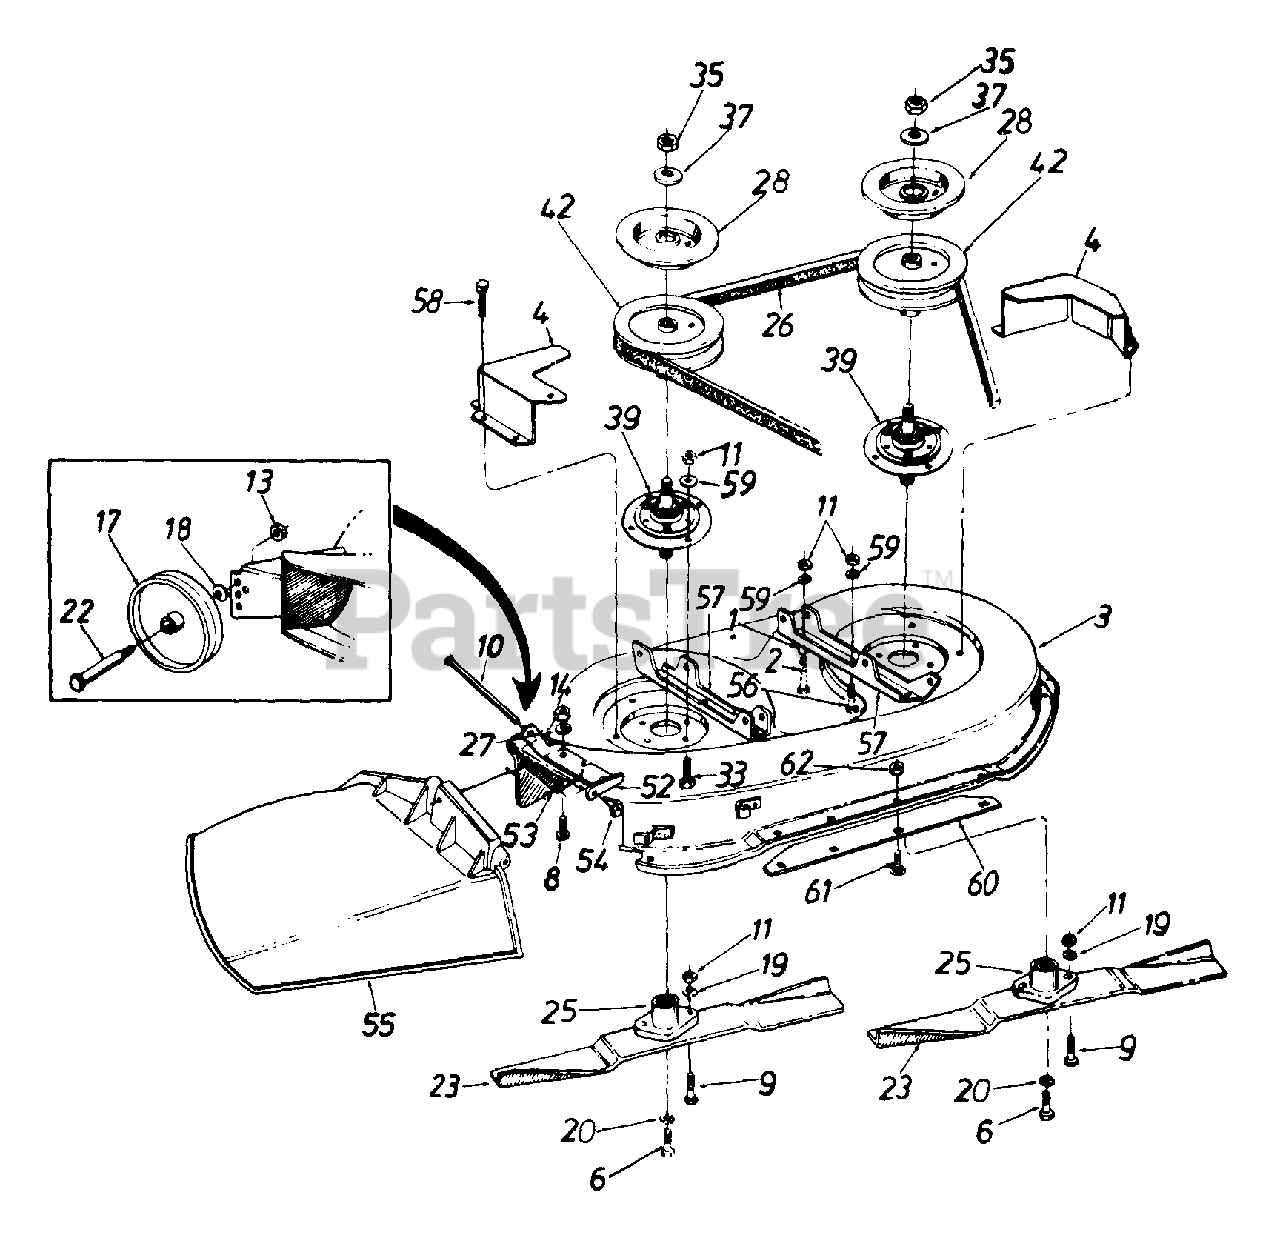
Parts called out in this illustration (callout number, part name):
1	Spacer .33" I.D. x .88"
2	Hex Bolt 5/16-24 x 1.25" Lg.
6	Hex Bolt 3/8-24 x 1.0" Lg.
8	Hex Bolt 1/4-20 x .62"
9	Hex Bolt Special 5/16-24 x 1.0"
10	Hinge Pin
11	Hex Nut 5/16-24 Thd.
13	Hex Top L-Nut 3/8-16 Thd.
14	Hex Nut 1/4-20 Thd.
17	Deck Wheel - 5"
18	Bell-Wash. .40" I.D. x .88" O.D.
19	L-Wash. 5/16" I.D.
20	L-Wash. 3/8" I.D. - H.D.
22	Shld. Bolt .498" Dia. x 1.53"
23	High-Lift Blade
25	Blade Adapter
26	V-Belt
27	Bell-Wash. 1/4" I.D.
28	Brake Disc
33	Hex Bolt 5/16-24 x .75" Lg.
35	Hex Jam Nut 5/8-18 Thd.
37	L-Wash. 5/8" I.D.
39	Blade Spindle Ass'y. Comp.
42	5" Dia. Pulley
52	Hinge Mtg. Brkt.
53	Torsion Spring
55	Chute Ass'y. Comp.
56	Hex Bolt 5/16-24 x .75" Lg.
59	Bell-Wash. .345" I.D. x .88"
62	Hex Sems Nut 1/4-20 Thd.
